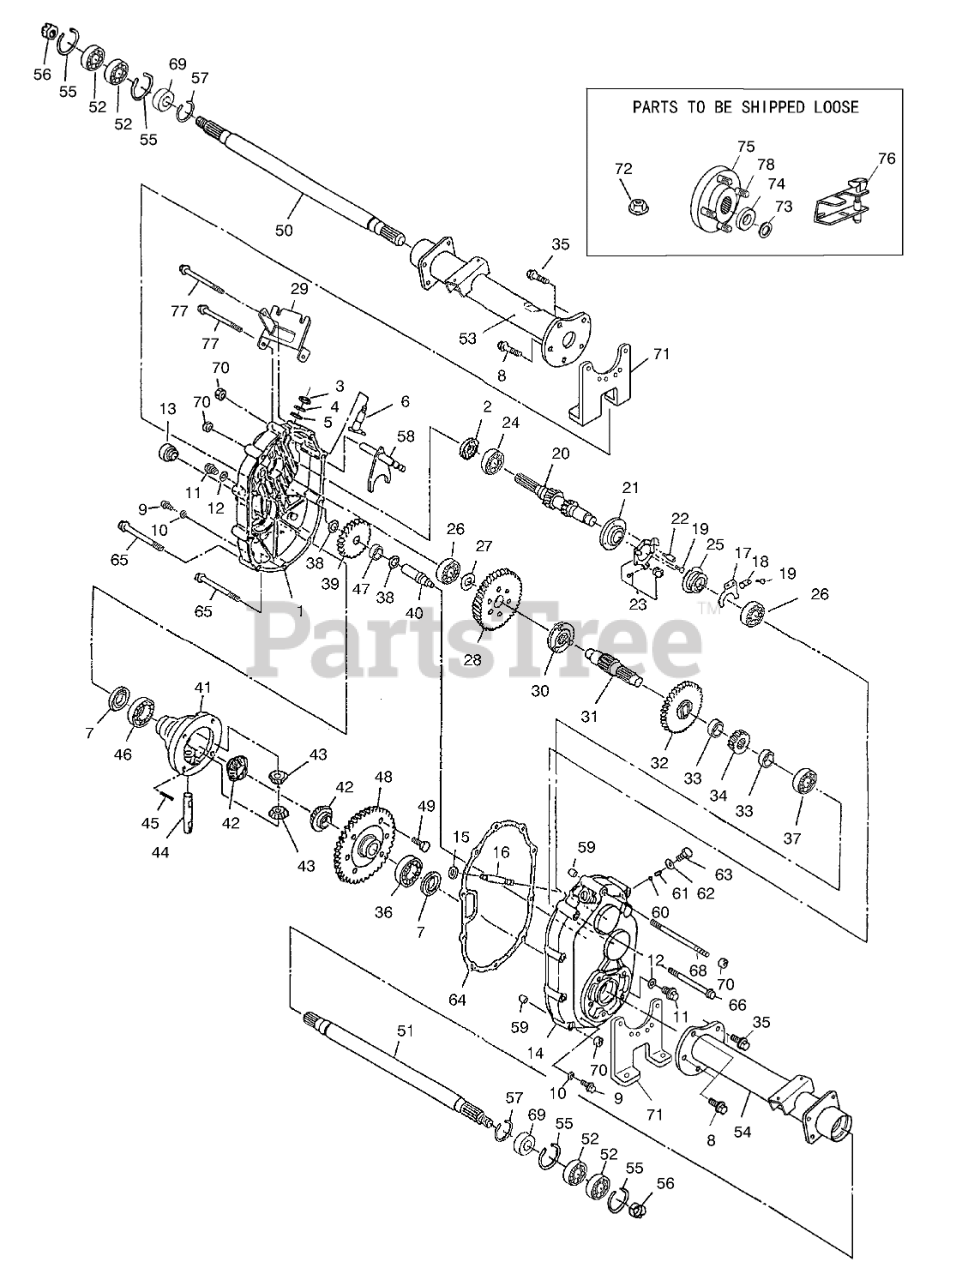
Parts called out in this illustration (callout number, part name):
1	CASE-LH, COMPLETE
2	SEAL-OIL
3	SEAL-OIL
4	RING-SNAP
5	SPACER
6	SHAFT-SELECTOR
7	SEAL-OIL
8	BOLT-FLANGE
9	PLUG-CHECK, OIL
10	GASKET
11	PLUG-DRAIN, OIL
12	GASKET
13	PLUG-FILLER, OIL
14	CASE-COMPLETE, RH
15	SEAL-OIL
16	SHAFT-GOVERNOR
17	FORK-GOVERNOR
18	STOPPER
19	SCREW AND WASHER ASM
20	Shaft-Input, Complete
21	BASE-GOVERNOR
22	PIN-LOCK
23	UNIT-PLATE, GOVERNOR
24	BEARING-BALL
25	SLEEVE-GOVERNOR
26	BEARING-BALL
27	SPACER
29	BRACKET-WIRE, CHANGE
30	CLUTCH-PIN
31	SHAFT-CENTER
33	COLLAR
35	BOLT-FLANGE
36	BEARING-BALL
37	BEARING-BALL
38	SPACER
40	SHAFT-COUNTER
41	CASE-DIFFERENTIAL
42	GEAR-SIDE, DIFFERENTIAL
43	PINION-DIFFERENTIAL
44	SHAFT-DIFFERENTIAL
46	BEARING-BALL
47	BEARING-NEEDLE
50	SHAFT-AXLE, LH
51	SHAFT-AXLE, RH
52	BEARING-BALL
53	CASE-AXLE, LH
54	CASE-AXLE, RH
55	RING-SNAP
56	NUT-CASTLE
57	RING-SNAP
58	SHAFT-SHIFT, COMPLETE
59	KNOCK-PIPE
60	BALL-STEEL
61	SPRING
62	GASKET
64	GASKET
65	BOLT-FLANGE
66	BOLT-FLANGE
69	COLLAR
70	NUT-HF
71	BRACKET-AXLE
72	NUT-LOCK
73	WASHER-SPRING
74	WASHER
76	Lever-Select
77	BOLT-FLANGE
